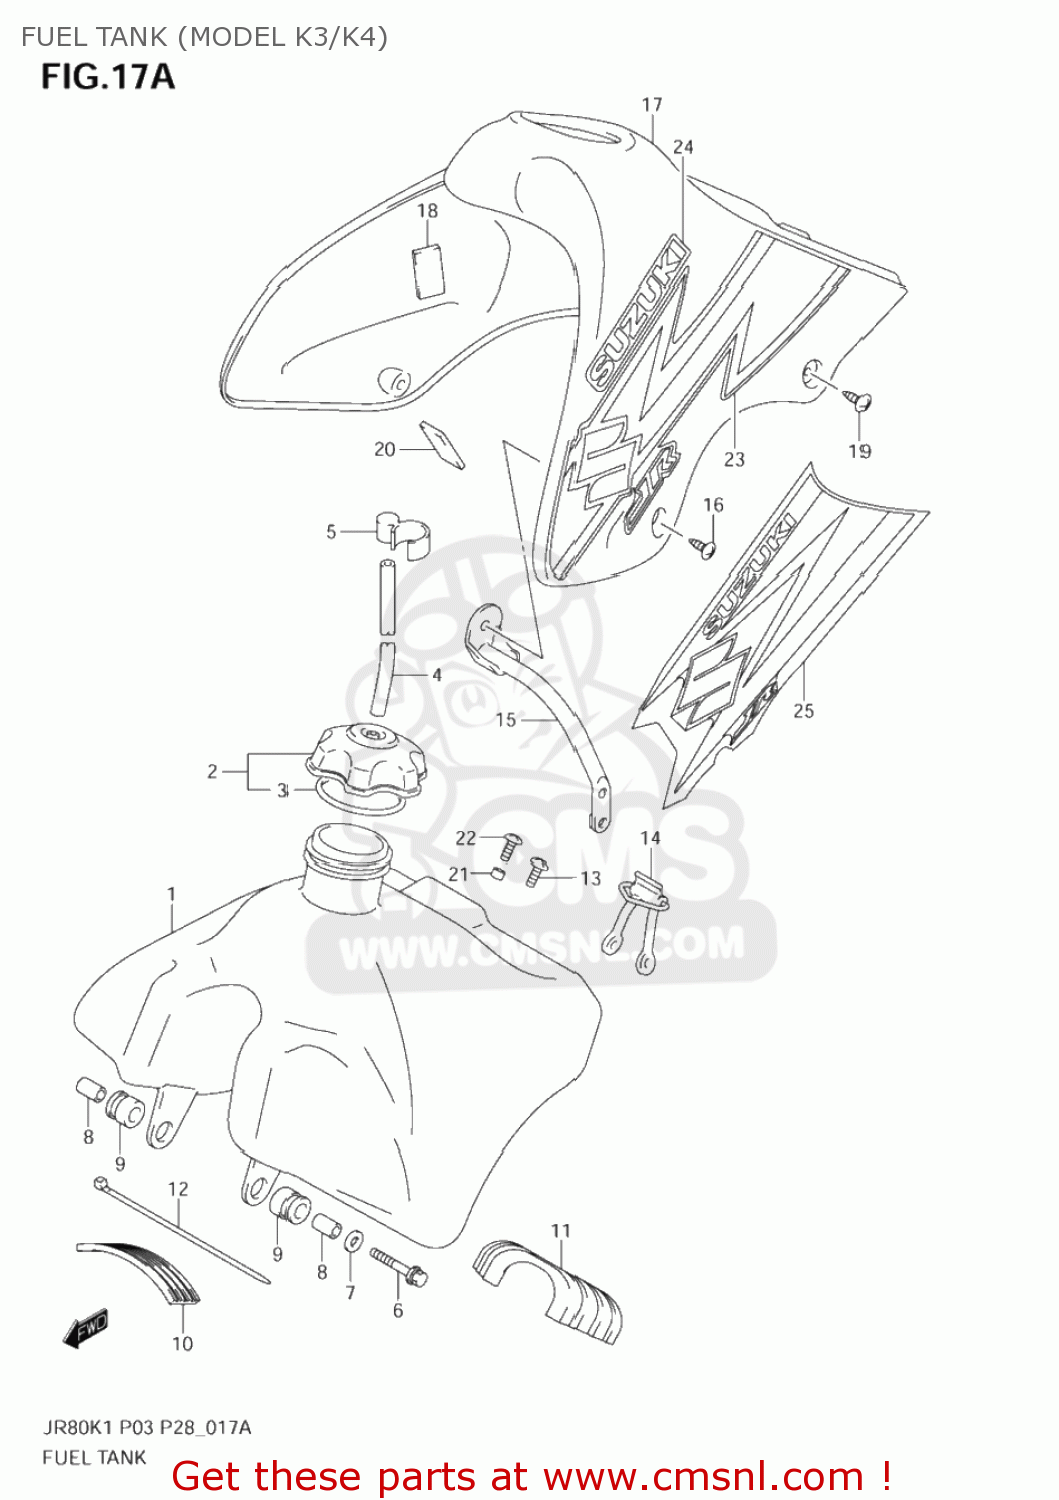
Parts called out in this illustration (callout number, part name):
1	TANK,FUEL
2	CAP SET,FUEL TANK
3	GASKET,CAP (NAS)
4	HOSE(5X8.2X600)
5	CLAMP
6	BOLT, FRONT
7	WASHER(6.5X18X1)
8	SPACER(6.5X10X16)
9	CUSHION
10	CUSHION,FUEL TANK UPR FR
11	CUSHION,FUEL TANK UPR RR
12	CLAMP(L:250)
13	SCREW
14	BAND,FUEL TANK RR
15	BRACKET,FUEL TANK COVER
16	SCREW(6X16)
17	COVER,FUEL TANK
18	CUSHION,FR FENDER
19	SCREW
20	CUSHION
21	SPACER(6.1X8X5.2)
22	BOLT
23	TAPE SET,FUEL TANK COVER
24	EMBLEM,SUZUKI
25	TAPE SET,FUEL TANK COVER
